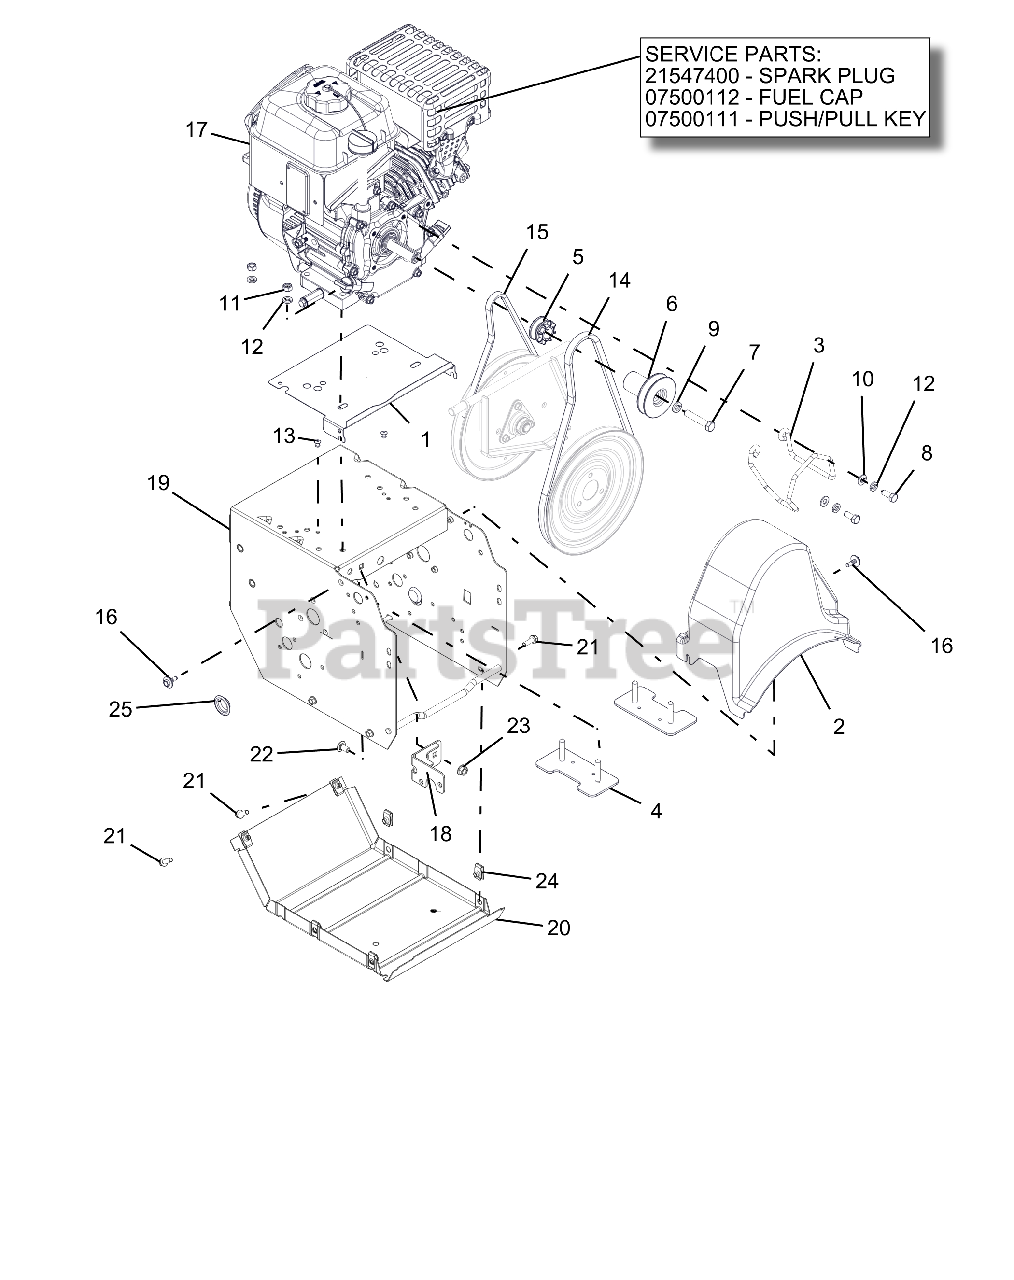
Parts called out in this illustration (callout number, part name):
1	BAFFLE,ENGINE,SMALL BLOCK
2	COVER, COMPACT BELT
3	FINGER, BELT
4	STRAP, ENGINE BOLT-WELDMENT
5	SHEAVE, TRACTION
6	SHEAVE,AUGER 3/4" PM
7	BLT-HEX .38-24X2.0 YWZC
8	BLT-HEX .31-24X.75 YWZC GR5
9	WSHR-LK .375X.115 HVY YWZC
10	@WSHR-FL-STL.344X.688X.065YWZC
11	@NUT-HEX .31-18 YWZC
12	WSHR-LK .312X.097 HVY YWZC
13	RVT-POP .187 YZ
14	V-BELT, HA-RAW EDGE
15	V-BELT, 3L-WRAPPED
16	SCR-TAP .25-20X.5 CAPTIVE
17	ENGINE, SNO-TEK 136 RECL
17	PLUG, SPARK
17	CAP, FUEL TANK BLACK
17	KEY, PUSH/PULL LCT (2/PACKAGE)
18	WELDMENT, FRAME BRACKET
19	WELDMENT,FRAME 920
20	COVER, BOTTOM
21	BLT-HEX .25-20X.75 HWH YZ GR5
22	@BLT-RHDSSQNK .31-18X.62 G5YZ
23	@NUT-LK-TOP-FLG .31-18 YWZC
24	NUT-RTNR .25-20X.56
25	PLUG, HOLE - 1.00" FLEXTEMP
